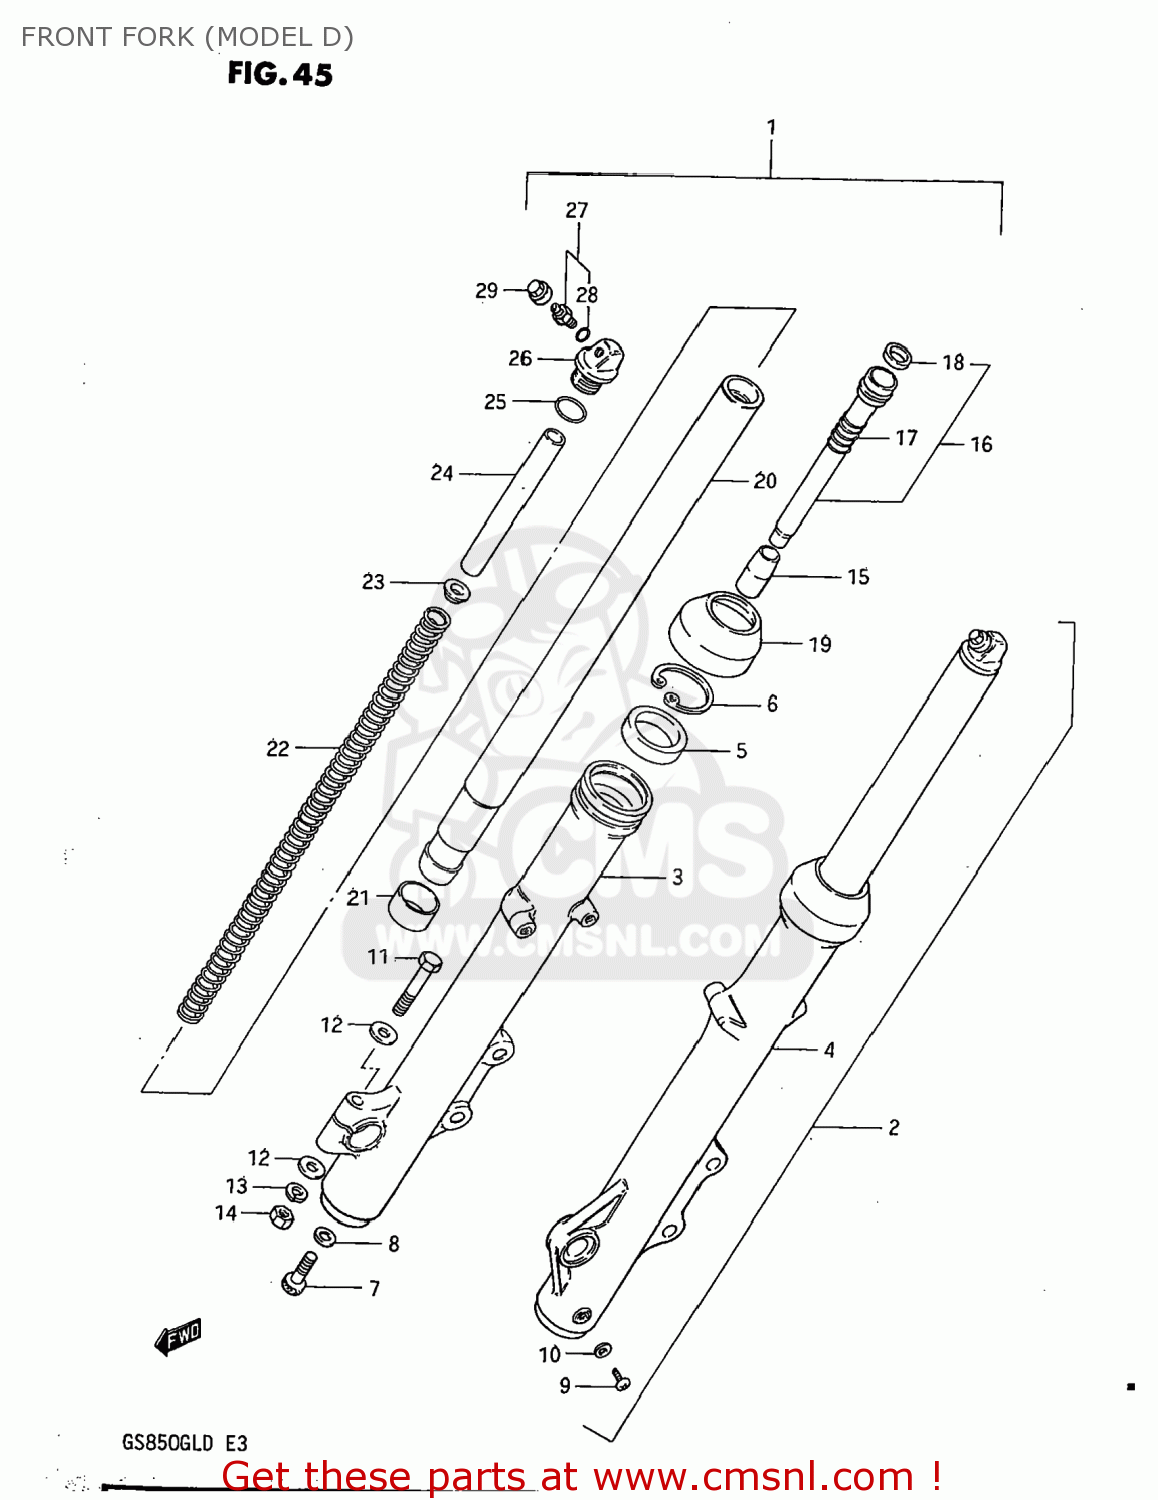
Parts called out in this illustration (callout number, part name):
1	DAMPER ASSEMBLY,RIGHT
2	DAMPER ASSEMBLY,LEFT
3	TUBE,FORK,OUTER,RIGHT
4	TUBE,OUTER,LEFT
5	OIL SEAL,FRONT FORK
6	RING,STOPPER
7	BOLT,FORK CYLINDER(10X25)
8	GASKET (NAS)
9	SCREW
10	GASKET,DRAIN,PLUG (NAS)
11	BOLT 8X50
12	WASHER
13	WASHER,LOCK,8.
14	NUT
15	PIECE,OIL LOCK
16	CYLINDER,FRONT FORK
17	SPRING,REBOUND
18	RING,PISTON
19	SEAL,DUST
20	TUBE,INNER
21	PISTON
22	SPRING,FRONT FORK
23	GUIDE,FRONT FORK SPRING C
24	COLLAR,SPRING
25	O RING
26	CAP,FORK INNER TUBE
27	VALVE
28	O RING
29	CAP,VALVE
